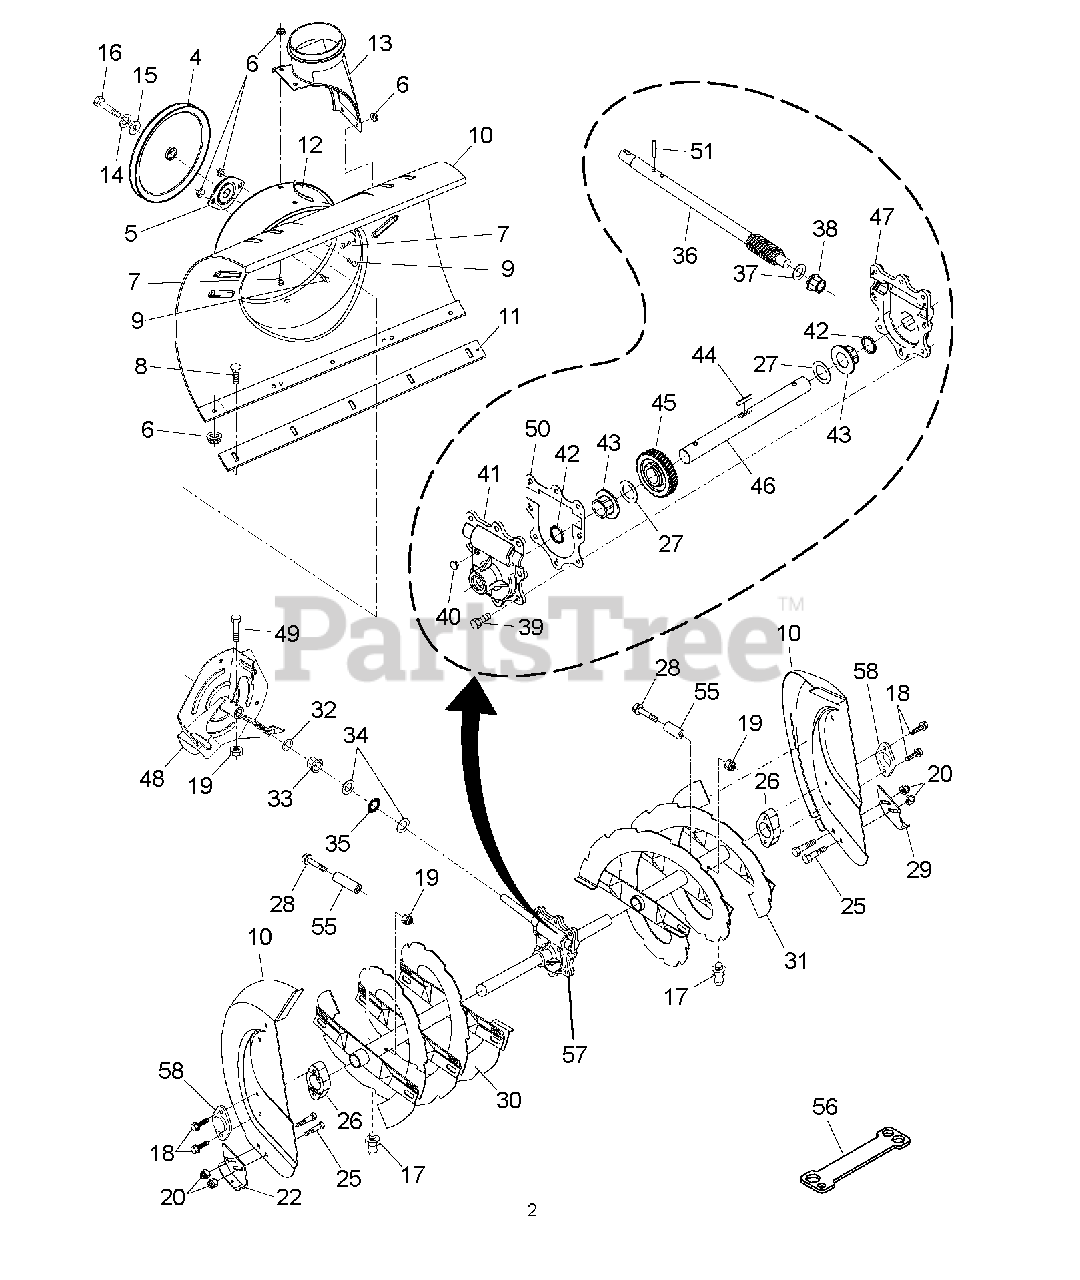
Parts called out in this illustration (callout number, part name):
4	PULLEY, IMPELLER
5	BEARING FLANGE
6	NUT, HEX FLANGE 5/16-18
7	BOLT.CARRIAGE.5/16-18X
8	BOLT
11	BAR, SCRAPER
12	BRACKET, CORNER DISCHARGE
13	BASE DISCHARGE CHUTE
14	WASHER, FLAT
15	LOCKWASHER
17	GREASE FITTING
18	SCREW, HEX HD 5/16X1
19	LOCKNUT
20	NUT, HEX FLANGE 5/16-18
22	SKID PLATE RH
26	BEARING.BALL.AUGER.SHAFT
27	WASHER TRUST 1"
28	BOLT, SHEAR
29	SKID PLATE LH
30	RP AUGER ASSEMBLY, RH
31	RP AUGER ASSEMBLY, LH
33	BUSHING, FLANGE 3/4
34	WASHER, THRUST 3/4
35	BEARING TRUST 3/4
36	SHAFT, IMPELLER
37	WASHER, THRUST 5/8
38	FLANGE BUSHING-5/8
39	HEX SCREW-5/16 X 3/4
40	CASE PLUG
41	GEARBOX HOUSING-RH
42	OIL SEAL
43	FLANGE BUSHING-1"
44	KEY, SQUARE 1/4 X .875
45	WORM GEAR
46	AUGER SHAFT
47	GEARBOX HOUSING - LH
48	IMPELLER ASSY
49	SCREW.HEX.HD1/4-20X
50	GEARBOX GASKET
51	PIN, ROLL 3/16 X 1-1/8
56	RP WRENCH, SNOWTHROWER
57	GEARBOX.ASSEMBLY.AUGER
58	BEARING RETAINER, PLASTIC
